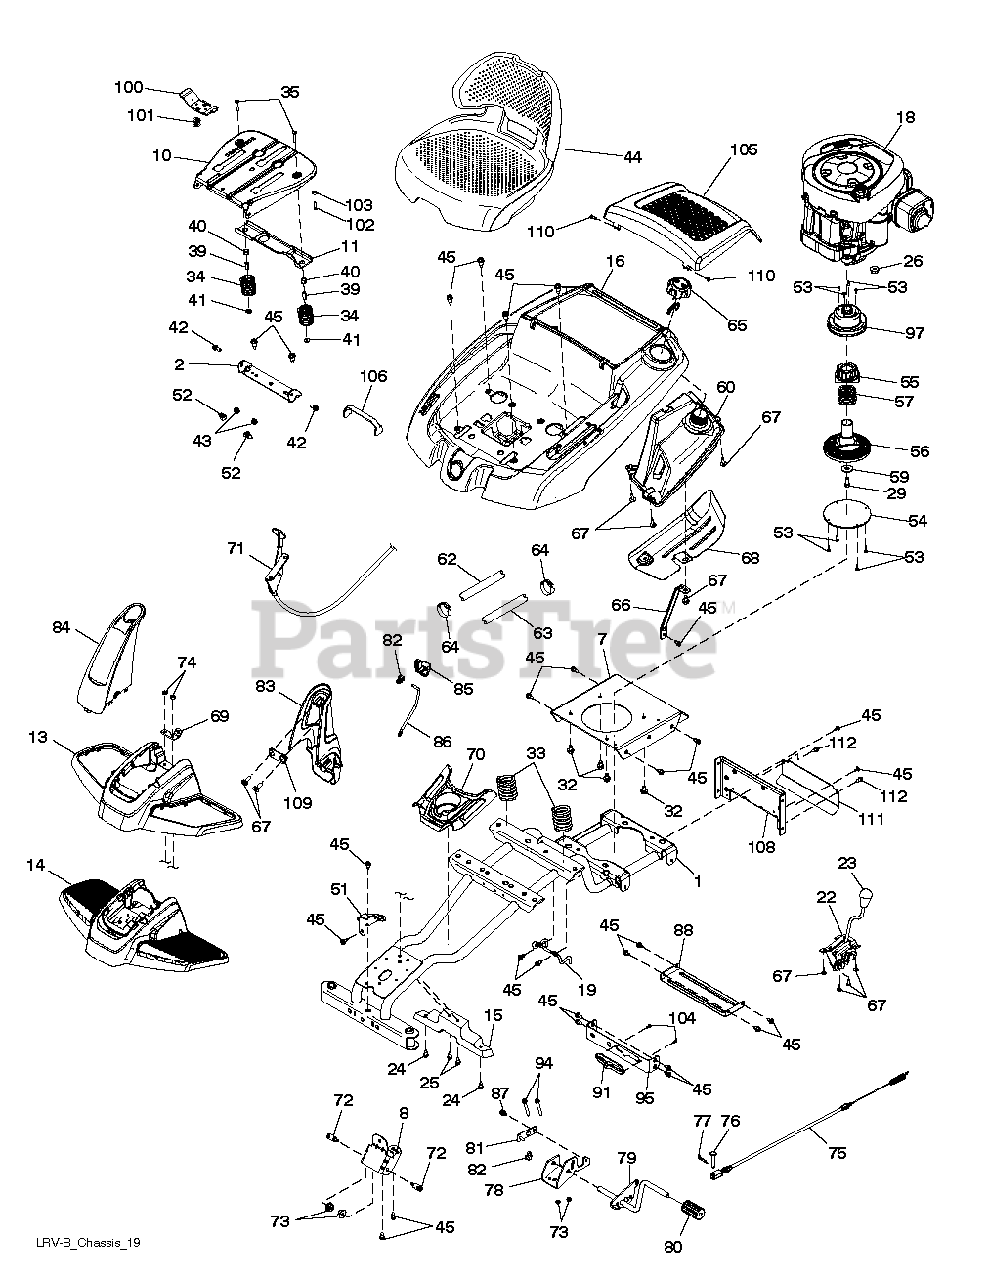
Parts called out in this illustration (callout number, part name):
2	BRKT.PIVOT.FENDER
8	BRACKET.SUSP.CHAS.FR.LRV
10	PAN.ASM.SEAT.SHORT.SLD.ADJ.TEX
11	BRKT.MNT.OPC.SW.SEAT.
14	FOOTREST.STRUCTURAL.
15	SUPPORT. FOOTREST.LRV.MS428
23	KNOB.OVAL.CUSTOM.BLACK
24	SCREW.#10 X 0.750.BOS (2 2)
25	BOLT.CARRIAGE
26	NUT
32	SCREW.3/8-16
33	SPRING COMPRESSION
34	SPRING COMPRESSED
35	BOLT.ROUND.HEAD.SQUARE.NECK
39	SPACER SPLIT 28X.96
41	NUT T
42	BOLT.SHOULDER.5/16-18
43	NUT.71038.31-18.HEX.NYLOCK
44	COMFORT.SEAT.ASSEMBLY
45	SCREW 5/16"
51	BRACKET, STEERING SUPPORT
52	PUSH CLIP
53	SCREW.#10X.750 *SUBS/2*
54	DISC.FRICTION.LRVB
55	TORSION.BODY.UPPER
56	TORQUE ASM.CONTROL.LOWER
57	SPRING.HELIX
59	WASHER.1.5X.505X.118
60	LRVB.FUEL.TANK.ASSEMBLY.EPA
63	RP PURGE LINE
64	HOSE CLAMP
65	CAP.2.25'.VENTED.RATCHET.EPA
67	SCREW.#10 X 0.500
70	CONSOLE.CENTER.CUPHOLDER
72	STUD.FASTNER.W/ANTI-ROTATE
73	NUT LOCK HEX FLANGE 5/16-18
74	NUT T
75	CABLE,BRAKE.LRVB
76	PIN.CLEVIS
77	COTTER PIN
80	COVER.PEDAL.BRAKE.LRV
82	RETAINER CLIP
87	BOLT.SHOULDER.5/16-18X
88	STRAP.CROSS.FRICTION.DRIVE
94	BOLT HEX FLGHD 5/16-18X3 GR. 5
100	HANDLE.SLIDE.SEAT.TEX.BLACK
101	SPRING.LATCH.SEAT.TEX
103	WASHER 13/32 X 2-3/8 X 12GA
104	SCREW.TORX.#10-14X1/2
105	MCCULLOCH.LRVB.ENGINE COVER
106	STRAP.BATTERY.LRVB
112	SCREW
